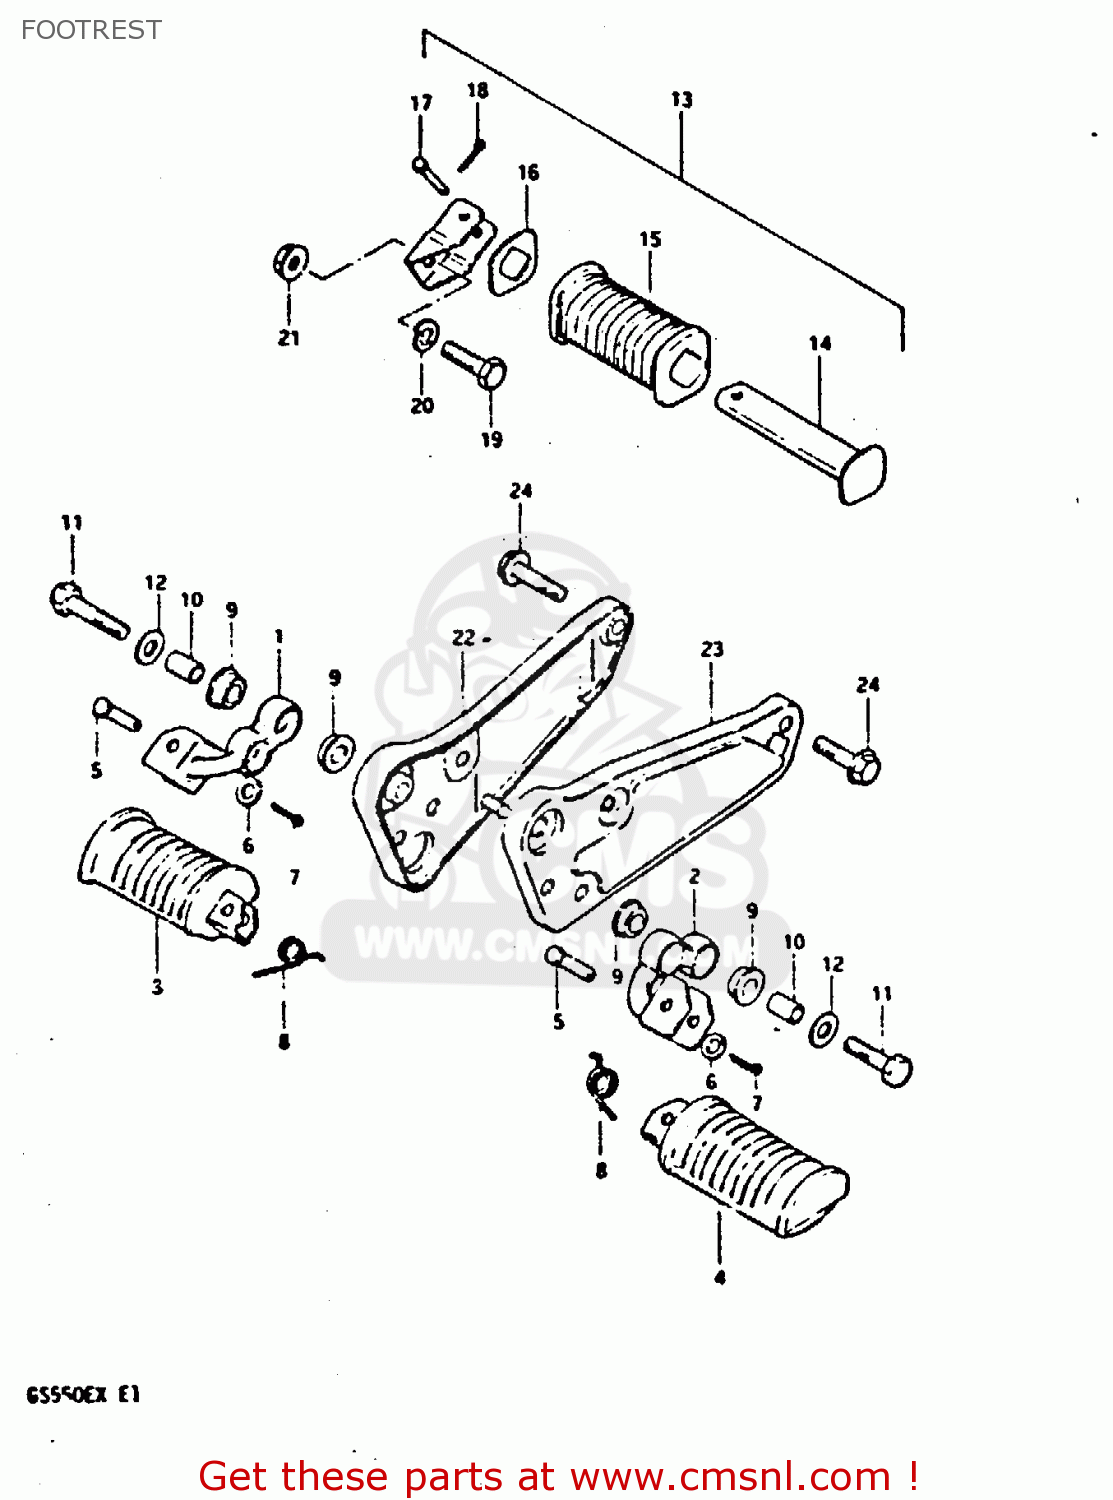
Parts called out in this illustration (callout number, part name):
1	BAR,FRONT FOOTREST
2	FOOTREST,FRONT,LEFT
3	RUBBER,PILLION FOOTREST,R
4	RUBBER,PILLION FOOTREST,L
5	PIN
6	WASHER
7	PIN
8	SPRING
9	BUSH
10	SPACER (10.2X14X20)
11	BOLT
12	WASHER(10.5X28X2.3)
13	FOOTREST ASSY,PILLION,R
14	BAR,REAR FOOTREST,LEFT
15	RUBBER,PILLION FOOTREST
16	WASHER,FOOTREST RUBBER
17	PIN
18	PIN
19	BOLT,M10X1.25X
20	LOCK WASHER
21	NUT
22	BRACKET,MUFFLER,RIGHT
23	BRACKET,MUFFLER,LEFT
24	BOLT
